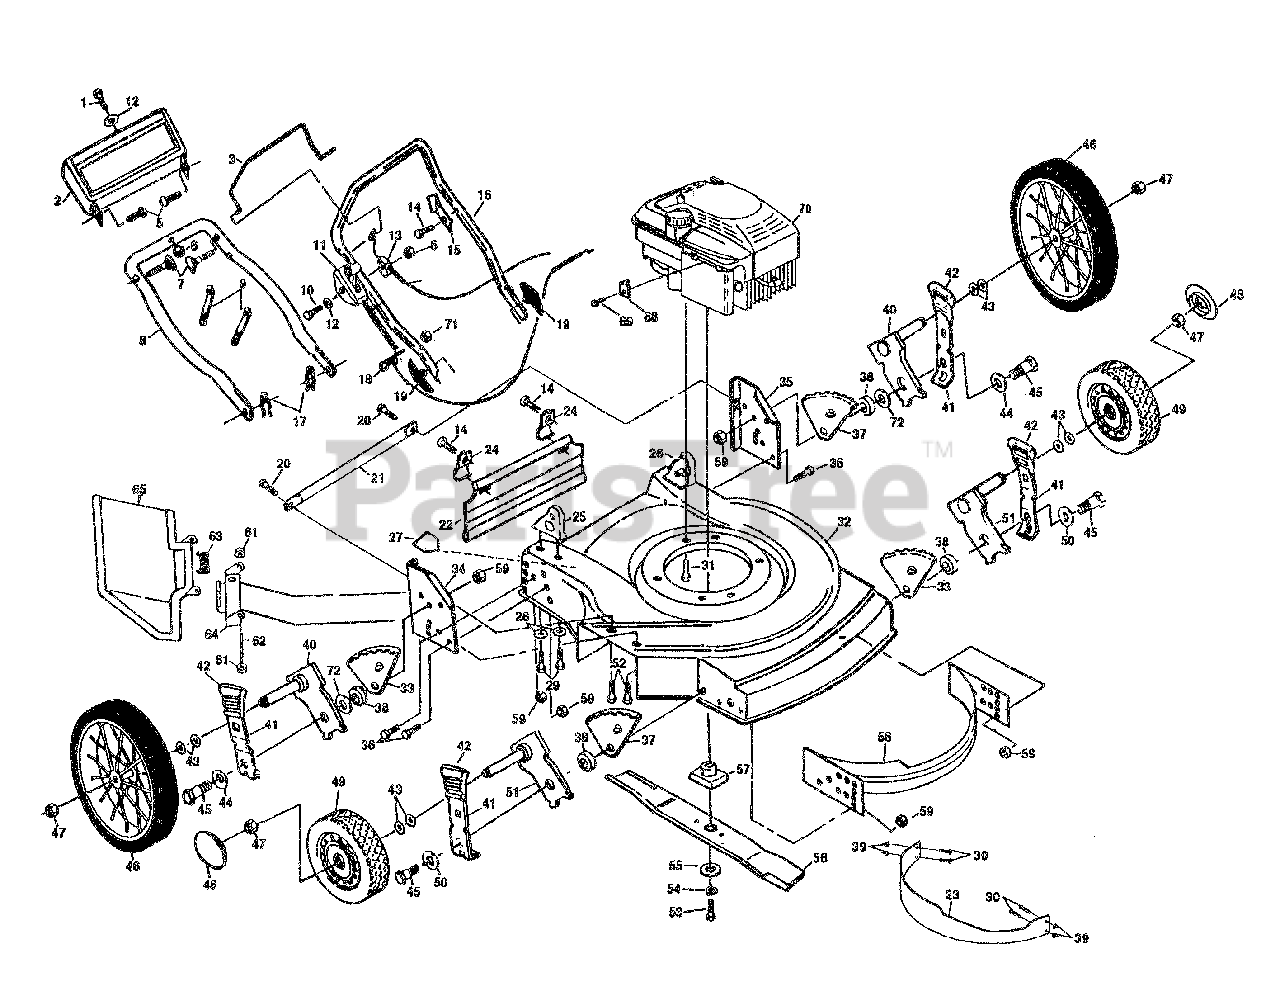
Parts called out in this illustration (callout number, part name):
1	Hex Head Washer Screw 1/4-20 x 1-1/2
2	Trim Plate
3	Control Bar
5	Self-tapping Screw #10-24 x 5/8
6	Locknut 1/4-20
7	Handle Bolt 5/16-1 x 1-3/4
8	Lower Handle
9	Wire Tie
10	Machine Screw 1/4-20 x 2-1/8
11	Throttle Control
13	Engine Zone Control Cable
14	Hex Washer Head Screw 10-24 x 1/2
15	Up-Stop Bracket
16	Upper Handle
17	Hairpin Cotter
18	Rope Guide
19	Handle Knob
20	Self-tapping Screw 1/4-20 x 1/2
21	Support Rod
22	Rear Skirt
23	Mulching Baffle
24	Skirt Bracket
25	Handle Bracket Assembly (Right)
26	Handle Bracket Assembly (Left)
27	Danger Decal
29	Thread Cutting Screw 5/16-18 x 1-3/4
30	Machine Screw
31	Thread Rolling Screw 3/8-16 x 1
32	Lawn Mower housing
33	Wheel Adjusting Bracket (LF/RR)
34	Wheel Support Bracket (Right)
35	Wheel Support Bracket (Left)
36	Hex Head Bolt 3/8-16 x 3/4
37	Wheel Adjusting Bracket (RF/LR)
38	Spacer
39	Hex Locknut
40	Axle Arm Assembly (Rear)
41	Selector Spring
42	Selector Knob
43	Washer
44	Washer
45	Shoulder Bolt 3/8-16
46	Wheel & Tire Assembly
47	Locknut
49	Wheel & Tire Assembly
51	Axle Arm Assembly (Front)
52	Hex W/Sems 1/4-20 x 3/8 Screw
53	Hex Head Screw 3/8-24 x 1-3/8 Gr. 8
54	Helical Washer 3/8
55	Hardened Washer
56	22" Blade
57	Blade Adapter
58	Front Baffle & Rear
59	Locknut 3/8-16
62	Hinge Rod
63	Torsion Spring
64	Housing Bracket Assembly
65	Discharge Guard
68	Cable Clamp
69	Thread Rolling Screw #10-32 x 5/8
71	Locknut, Keps 1/4-2
72	Flat Washer 3/8
